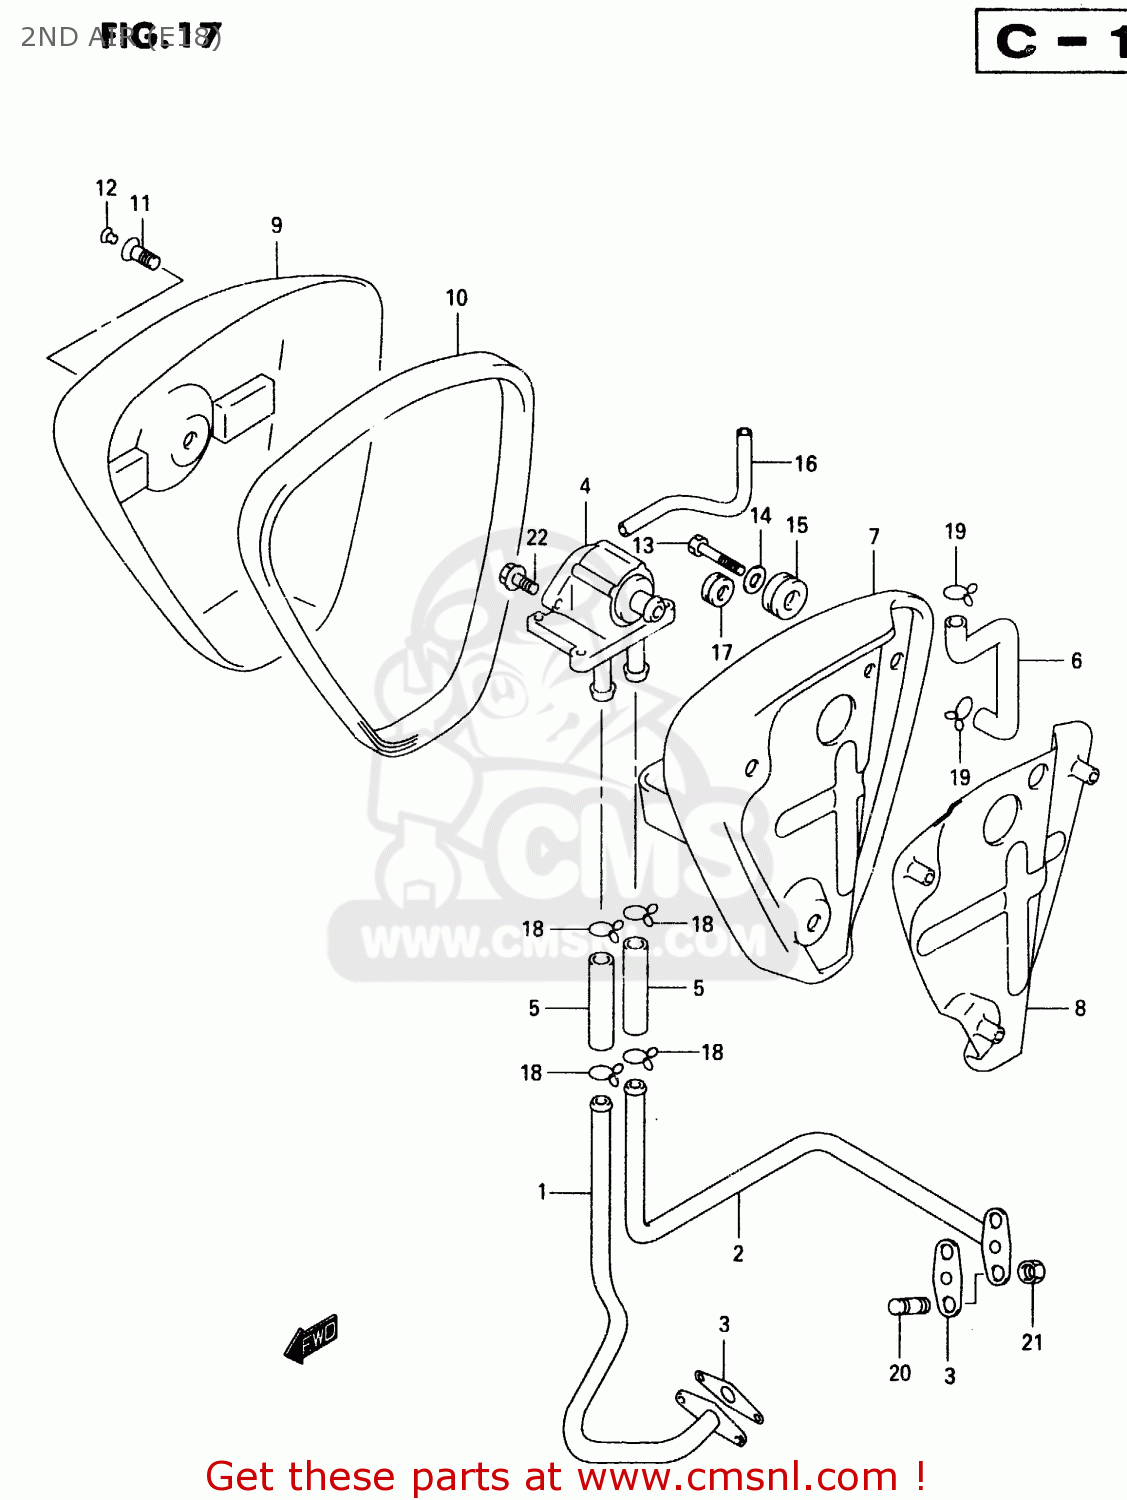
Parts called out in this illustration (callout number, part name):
1	PIPE,2ND AIR FR
2	PIPE,2ND AIR RR
3	GASKET,SECOND AIR PIPE (N (NAS)
4	VALVE ASSEMBLY,SECOND AIR
5	HOSE,SECOND AIR VALVE
6	HOSE,2ND AIR CLEANER
7	BRACKET,2ND AIR SPRT
8	PLATE,2ND AIR HEAT GUARD
9	COVER ASSY,2ND AIR
10	CUSHION
11	BOLT(8X25)
12	CAP(OD:11)
13	BOLT
14	WASHER
15	CUSHION
16	HOSE(3.5X7.5X600)
17	CUSHION
18	CLIP
19	CLIP
20	STUD BOLT
21	NUT
22	BOLT
